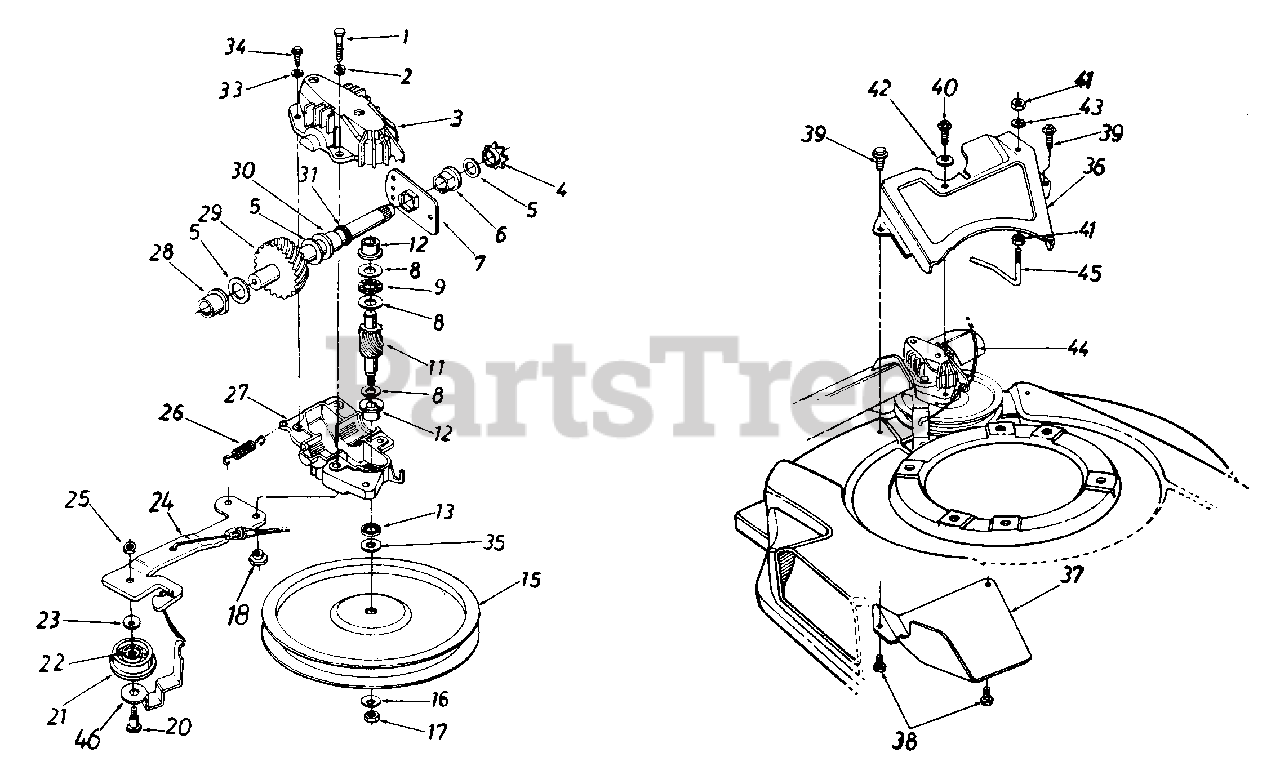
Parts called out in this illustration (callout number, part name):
1	Hex Patch Bolt 1/4-20 x 1.25" Lg.
2	L-Wash. 1/4" I.D.
3	Upper Hsg. Half
4	#48 Sprocket 7 Tooth x 1/2 Pitch
5	Fl-Wash. 58" I.D. x .030
6	Hex Flange Brg. .631" I.D.
8	Thrust Wash. .382" I.D. x .70" O.D.
9	Thrust Bearing .375" I.D. x .812" O.D.
11	11 Tooth Helical Gear
12	Flange Bearing
13	Oil Seal
15	Fl-Pulley 5.06" I.D.
16	Bell-Wash. .265" I.D. x .75"
17	Hex Nut 1/4-28 L.H. Thd.
18	Shld. Spacer .375" Dia. x .170
20	Shld. Bolt .375" Dia. x .40"
21	Fl-Idler Plastic 1.50" Dia.
22	Needle Brg. .375" x .735"
23	Bell-Wash. .265" I.D. x .75"
24	Idler Brk't. Ass'y.
25	Hex Patch L-Nut 1/4-28 Thd.
26	Extension Spring 1.12" Lg.
27	Lower Hsg. Half
28	Flange Bearing .56 Dia.
29	Shaft Ass'y.
30	Flange Bearing .629 Dia.
31	Oil Seal .625 Dia.
33	L-Wash. #10 I.D.
34	Hex B-Tap Scr. #10 x .62"
35	Hex Washer .26" x .88"
39	Hex AB-Tap Scr. 1/4 x .50" Lg.
40	Hex B-Tap Scr. 1/4 x .62" Lg.
41	Hex Nut 1/4-20 Thd.
42	Bell-Wash. .265" I.d. x .75"
43	L-Wash. 1/4" I.D.
44	S.P. Cable - 48" Lg.
45	S.P. Belt Guard
46	Belt Keeper
